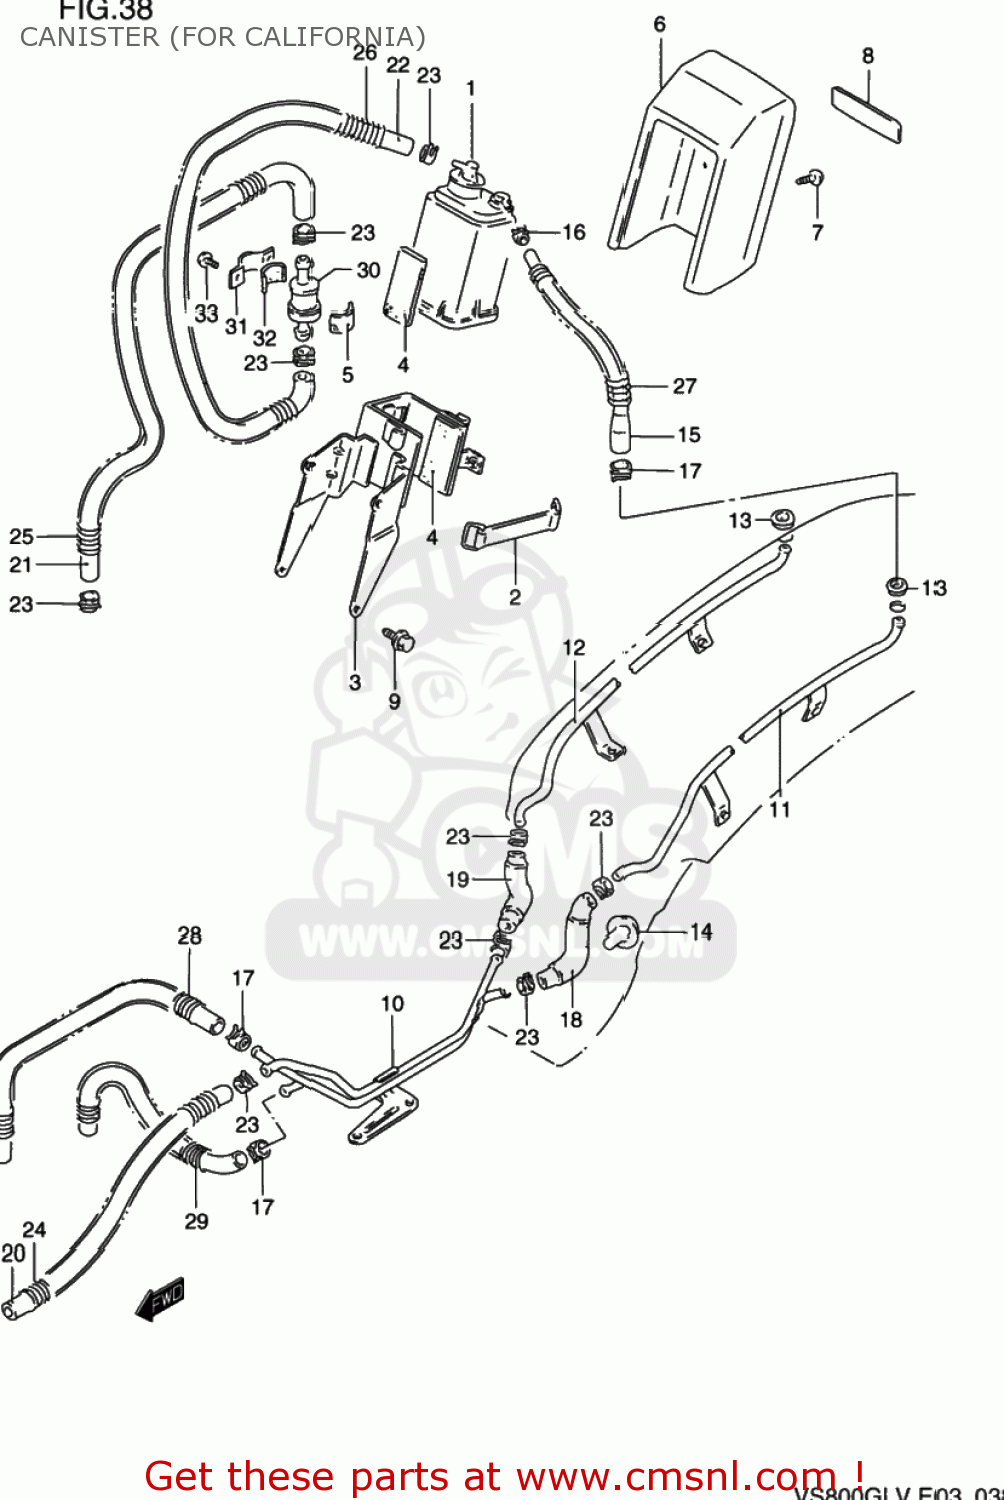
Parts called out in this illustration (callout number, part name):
1	CANISTER ASSY,CHARCOAL
2	BAND
3	BRACKET,CANISTER
4	CUSHION
5	CUSHION
6	COVER,CANISTER
7	SCREW
8	EMBLEM,TOOL HOLDER RR
9	BOLT
10	PIPE,CSTR JOINT FR
11	(CA) PIPE,CANISTER JOINT REAR
12	(CA) PIPE,CANISTER JOINT REAR
13	GROMMET
14	GROMMET
15	HOSE,PURGE NO.1
16	CLIP
17	CLIP
18	(CA) HOSE NO.6
19	(CA) HOSE NO.2
20	HOSE(5.4X11.4X600)
21	HOSE
22	HOSE
23	CLIP
24	SPRING
25	(CA) SPRING
26	SPRING
27	SPRING
28	SPRING
29	SPRING
30	VALVE,FUEL TANK BREATHER
31	PLATE,FUEL TANK BREATHER NO.2
32	CUSHION
33	SCREW
